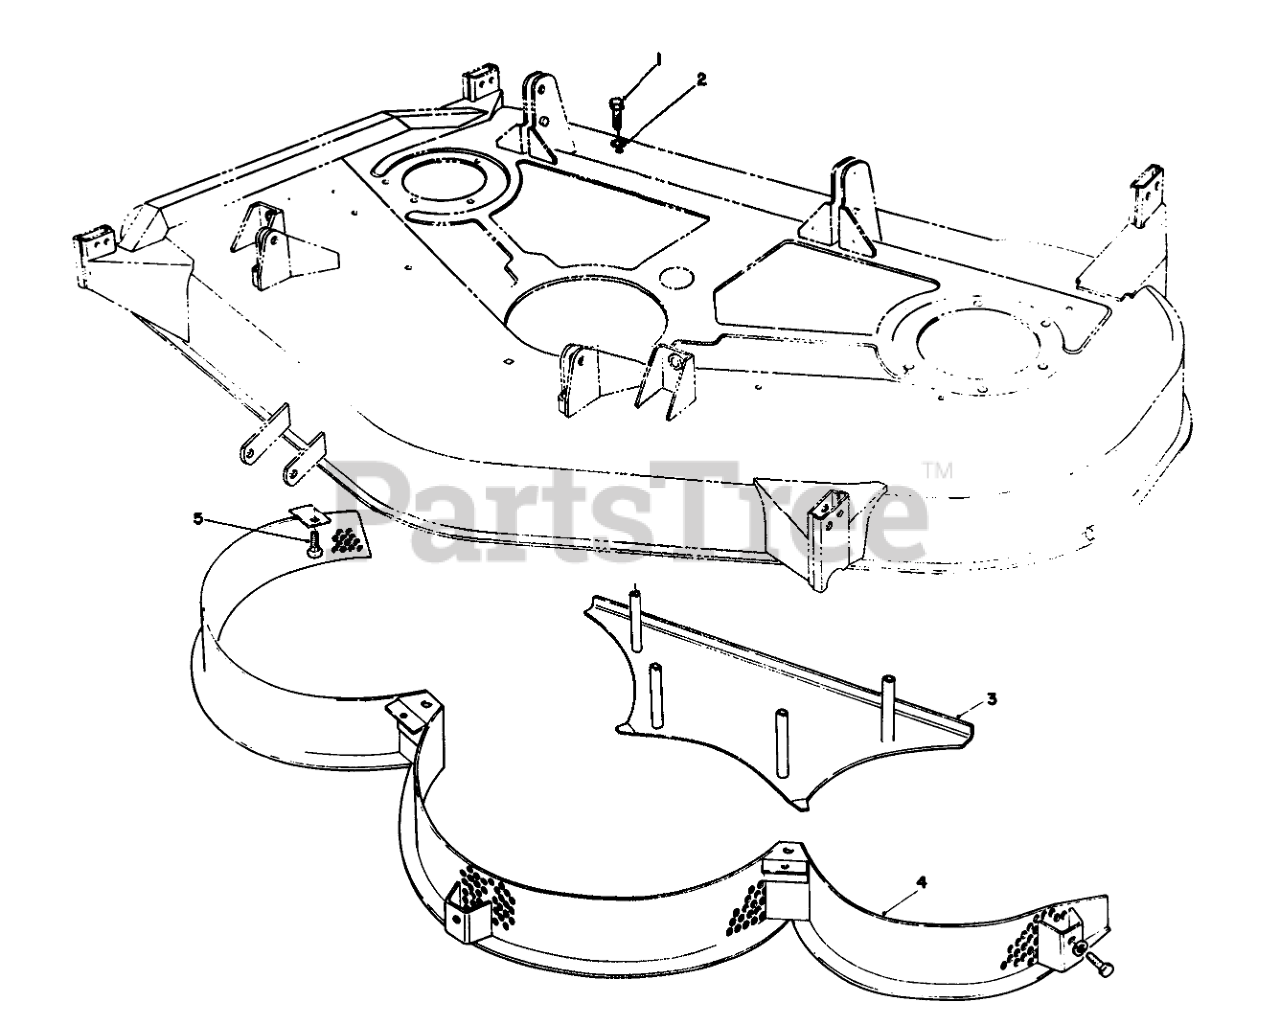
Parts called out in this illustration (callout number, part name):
1	SCREW-HH
2	WASHER-LOCK
3	Bottom Rear Shelf
4	Mulcher Screen
5	BOLT-CARR
